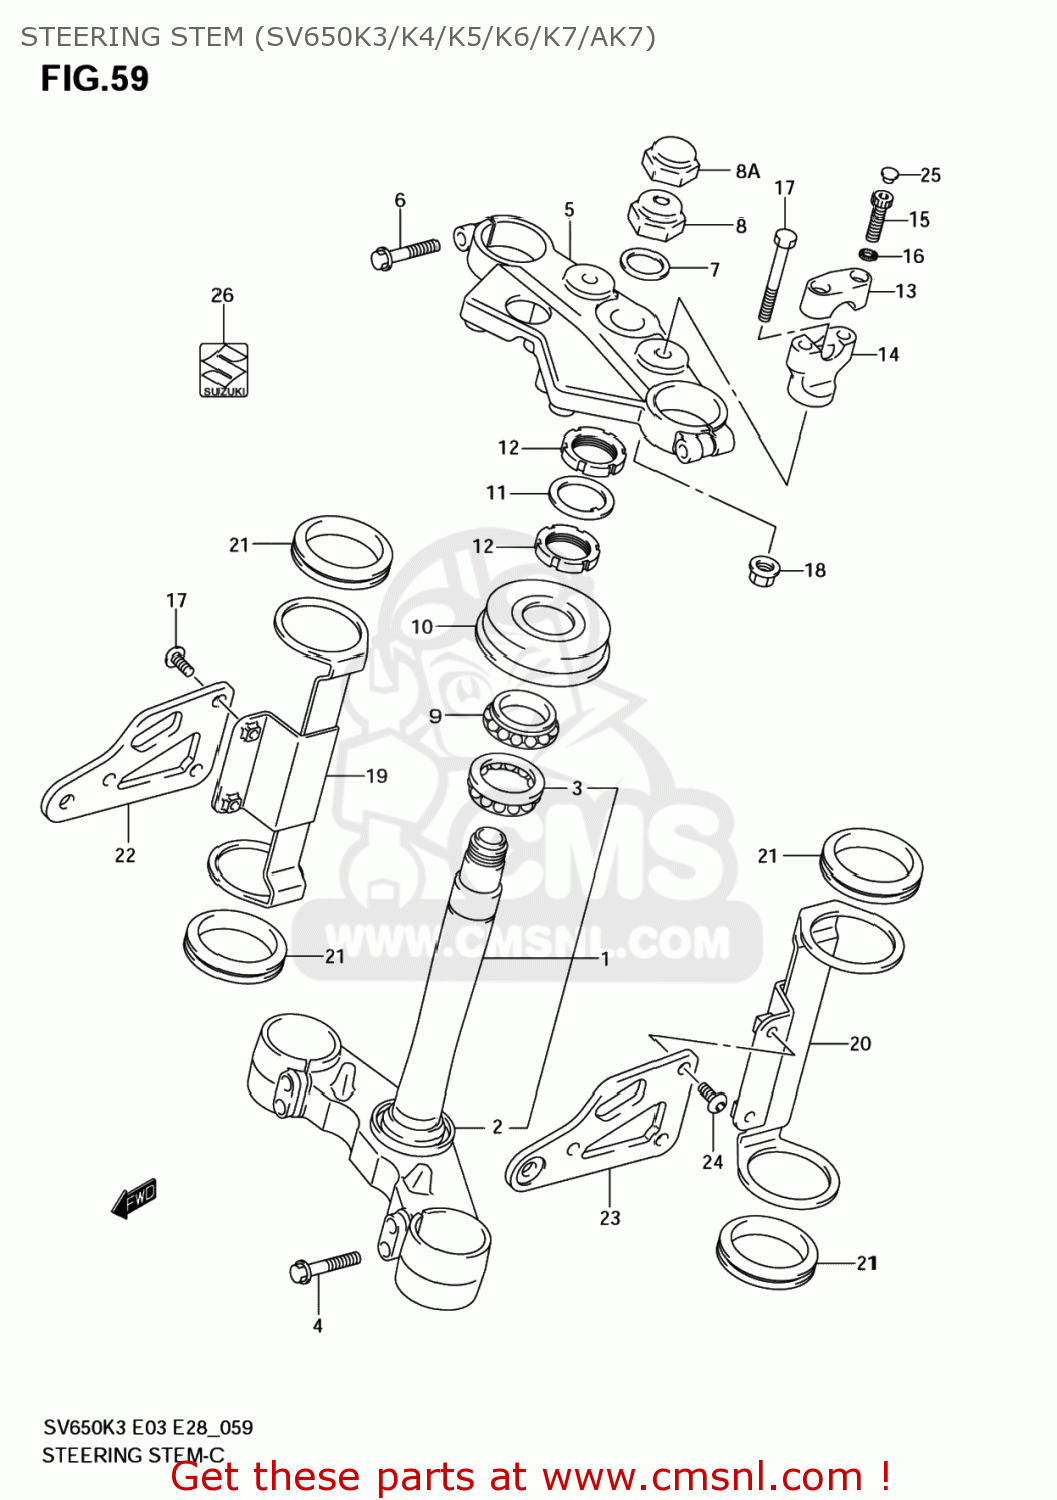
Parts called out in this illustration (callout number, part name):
1	STEM,STEERING
2	SEAL,STEERING LWR
3	BEARING(30X55X17)
4	BOLT(8X40)
5	HEAD,STEERING STEM
6	BOLT(8X40)
7	WASHER
8	NUT
8A	NUT
9	BEARING(30X55X17)
10	SEAL,STEERING UPR DUST
11	WASHER,STEERING STEM
12	NUT,STEERING STEM
13	HOLDER,HANDLE
14	HOLDER,HANDLE UNDER
15	BOLT
16	WASHER
17	BOLT
18	NUT
19	BRACKET,HEADLAMP HOUSING,R
20	BRACKET,HEADLAMP HOUSING,L
21	DAMPER,HEADLAMP HSG BRACKET
22	STAY,HEADLAMP HOUSING,R
23	STAY,HEADLAMP HOUSING,L
24	SCREW(6X16)
25	CAP(OD:11)
26	EMBLEM,S
